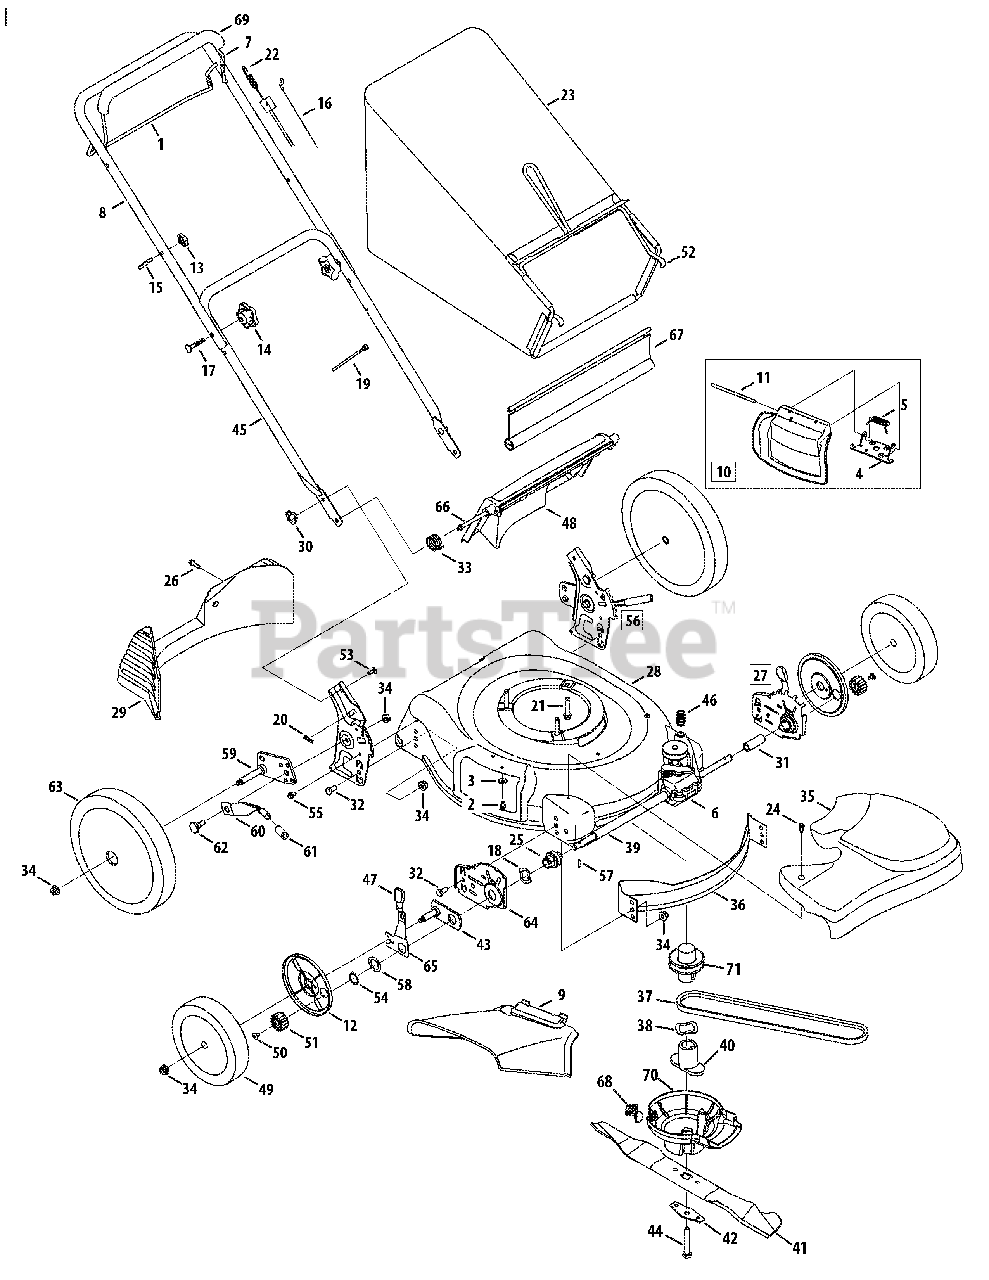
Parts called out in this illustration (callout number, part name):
1	Drive Control
2	TT Screw 1/4-20 x 0.5
3	Bell Washer.265 x 0.75
4	Deflector Chute Adapter
5	Torsion Spring
6	Transmission Assembly
7	Blade Control
9	Chute Deflector
10	Mulch Plug Complete
11	Hinge Pin
12	Wheel Dust Cap
13	Handle Knob
14	Star Knob
16	Control Cable - 40.75"
17	Carriage Bolt 5/16-18 x 2.0
18	Wave Washer, 1.5 x 1.0 x .029
19	Cable Tie
20	Cotter Pin
21	Self-Tapping Sems Screw
22	Drive Cable - 51"
23	Grassbag Assembly
24	Shoulder Screw # 12 -24
25	Front Bearing Assembly
26	Screw, 1/4-15 x 1.000
27	Height Adjustment Ass’y - RH
27	Height Adjustment Ass’y - LH
29	Rear Baffle
30	Wing Nut
31	Slev. Spacer 1.4" Lg.
32	Hex Screw, 3/8-16 x.75
33	Torsion Spring - RH
34	Flange Lock Nut, 3/8-16
35	Transmission Cover
36	Front Baffle
38	Washer, Wave, 1.351 x 1.051 x .015
39	Sleeve Spacer 8.985" Lg.
40	Blade Adapter
41	21" Mulching Blade
42	Blade Bell Support
43	Pivot Plate Assembly
44	Hex Screw 3/8-24 x 2.50
46	Belt Tension Spring
47	Adjustment Knob
48	Rear Discharge Door
49	Front Wheel
50	Screw, 1/4-20 x .390
51	Gear 14T RH FWD
51	Gear 14T LH FWD
53	Carriage Bolt 1/4-20
54	Snap Ring
55	TT Scr. w/Washer 1/4-20 x.625
56	Handle Bracket Assembly - LH
56	Handle Bracket Assembly - RH
57	Dowel Pin
58	Washer, Flat, 1.01 x 1.50 x .035
59	Pivot Arm Assembly - RH
59	Pivot Arm Assembly - LH
60	Rear Spring Lever
61	Foam Grip
62	Shoulder Scr.500 Dia. x.434
63	Rear Wheel
64	Height Adjuster Plate - RH
64	Height Adjuster Plate - LH
65	Front Lever - RH
65	Front Lever - LH
67	Rear Trailing Shield
68	Engine Baffle Bracket
69	Deluxe Bail Cover
70	Engine Baffle
71	Pulley Assembly, Drive
